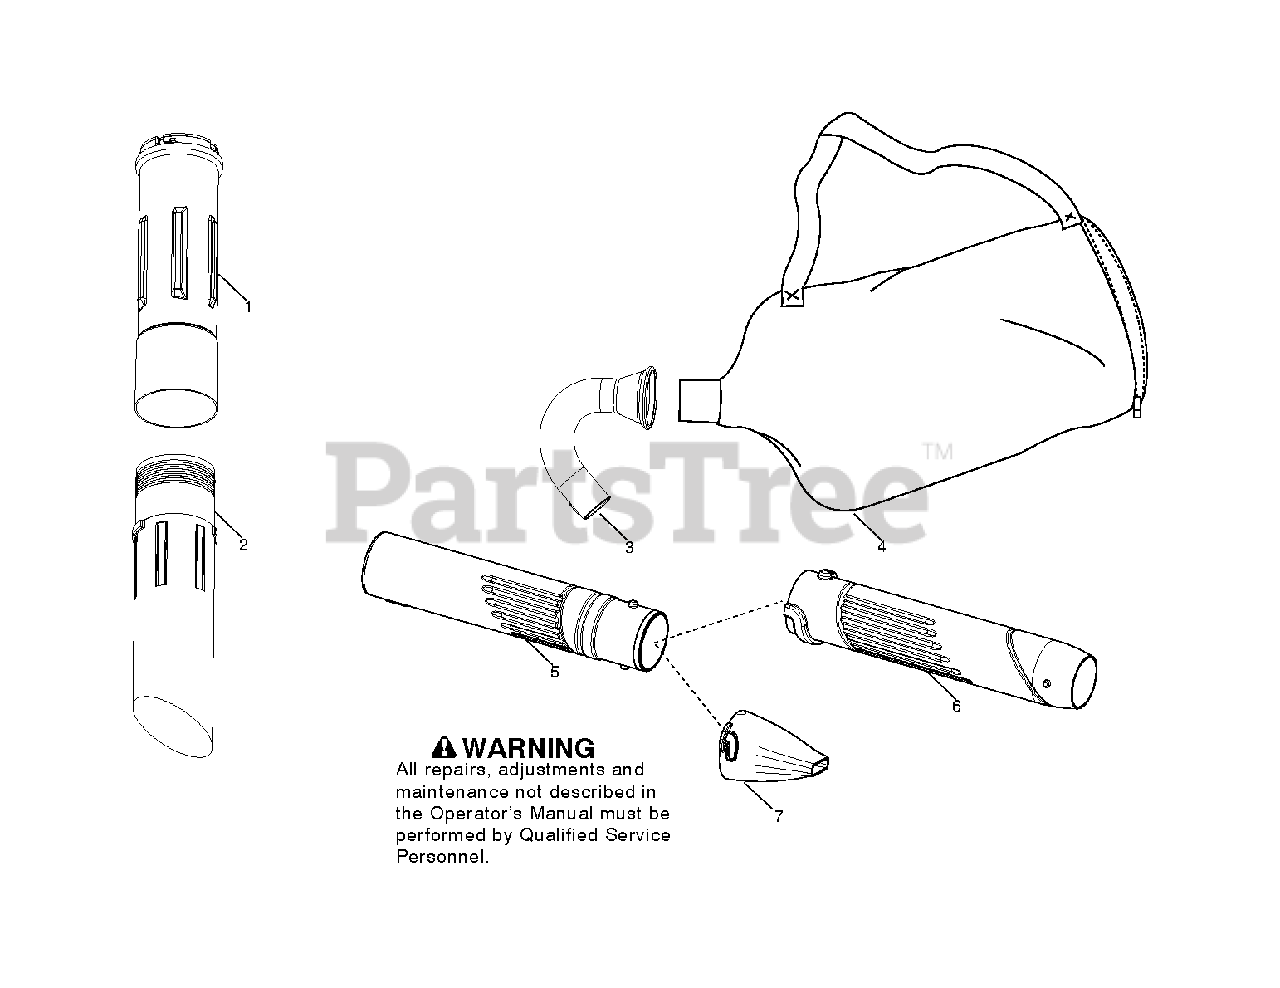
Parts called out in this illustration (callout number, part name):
1	TUBE VAC UPPER BLACK
2	TUBE LOWER VAC
3	TUBE VACUUM J BLACK
4	ASSY VAC BAG GAS W/STRAP
5	TUBE BLOWER SUPPER W BLACK
6	TUBE BLOWER LOW END BLACK
7	NOZZLE BLACK HI SPEED ADAPTOR
